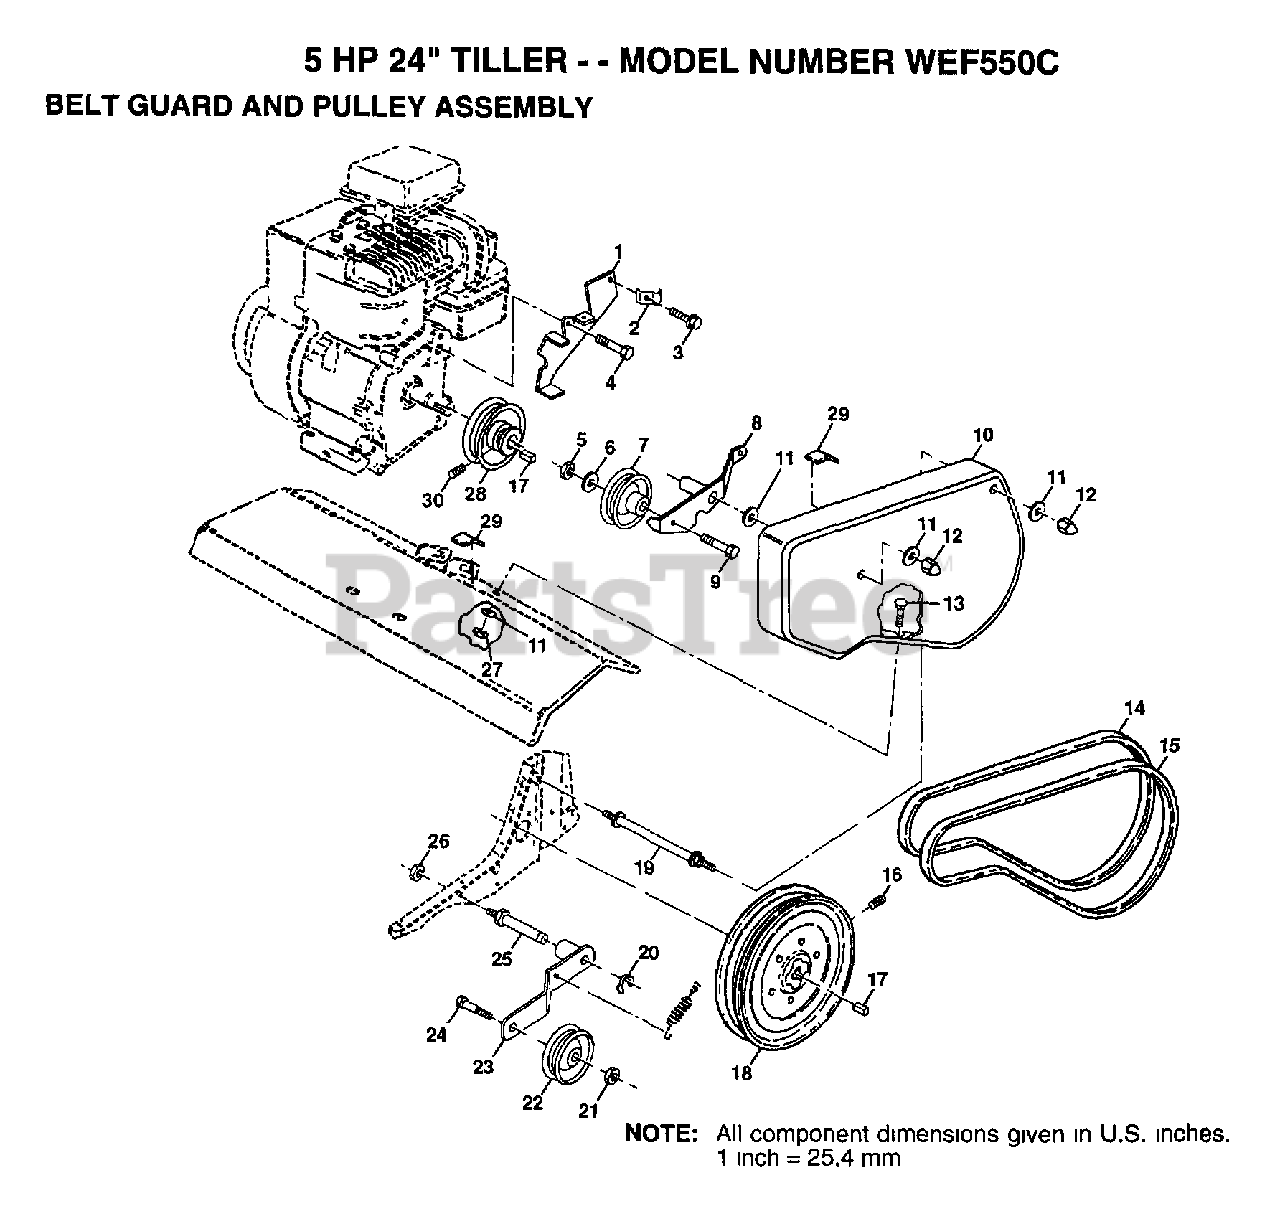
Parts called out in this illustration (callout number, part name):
2	CONDIUT CLIP T
5	NUT.HEX.3/8-16UNC
6	WASHER
7	PULLEY W/SPACER
8	ARM.ASM.REV.IDLER
11	WASHER
12	NUT-CAP TI
13	BOLT T
14	BELT-V
16	SET SCREW
17	KEY T
19	BOLT TI
20	KLIP RING TI
21	NUT
23	IDLER ARM TI
25	SHAFT IDLER TI
26	JAM NUT TI
27	NUT
28	ENGINE PULLEY TI
29	PAD IDLER TI
30	SET SCREW
